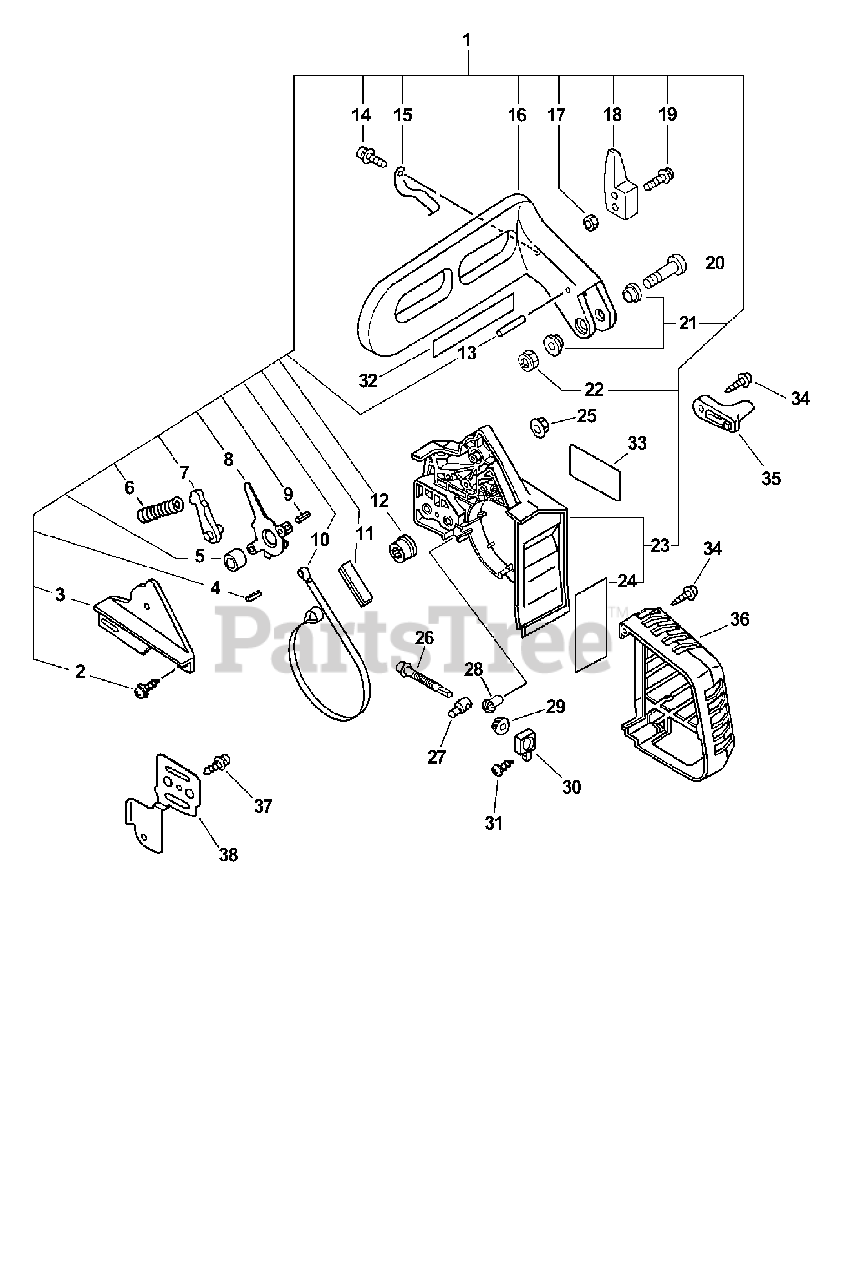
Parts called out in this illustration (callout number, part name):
1	CHAIN BRAKE ASSY
2	SCREW 4×12
3	COVER, BRAKE
4	PIN, SPRING 2.5×12
5	SPACER 8×12×9
6	SPRING, COMPRESSION
7	STOPPER, BRAKE
8	LEVER, BRAKE
9	PIN, SPRING 4×8.8
10	BAND, BRAKE
11	SEAL, BRAKE
12	ADJUSTER, BRAKE
13	ROLLER 4×23.8
14	SCREW 4×12
15	SPRING, FLAT
16	LEVER, BRAKE
18	WEIGHT, BRAKE
19	SCREW 4×22
20	SCREW 5×32
21	COLLAR 5.3×10×13×L5
22	NUT, LOCK M5
23	GUARD, SPROCKET - GRAY
24	SHIELD, HEAT 35×60×0.10
25	NUT, FLANGE M6
27	TENSIONER, CHAIN
28	GEAR, BEVEL
29	GEAR, BEVEL
30	COLLAR 8
31	SCREW 4×12
32	LABEL - BAR & CHAIN
32	LABEL, BAR & CHAIN
33	LABEL, MODEL
34	SCREW, TAPPING 5×20
35	CHAIN CATCHER
36	COVER, MUFFLER
37	SCREW 4×10
38	PLATE, GUIDE
